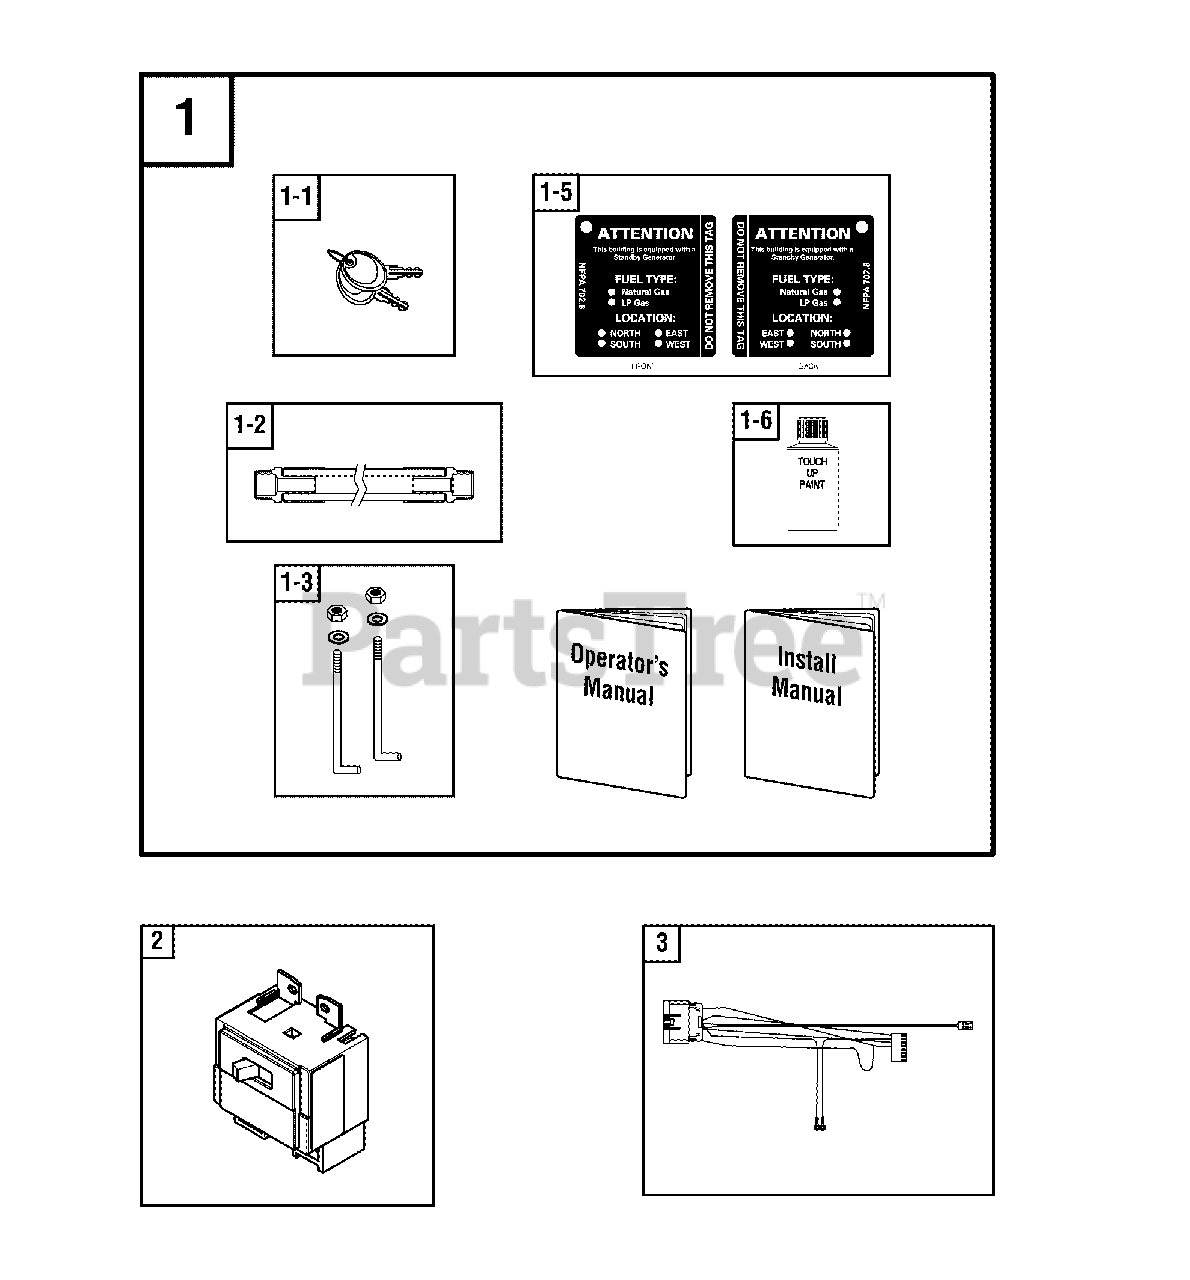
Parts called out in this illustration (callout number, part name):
1	KIT-MANUAL, ACC
1-3	KIT-HOLD DOWN, BATTERY
1-5	DECAL-ATTN STANDBY EQUIPMENT
1-6	PAINT-TOUCH-UP, ALMOND TEXTURE
2	BREAKER-CIRCUIT
